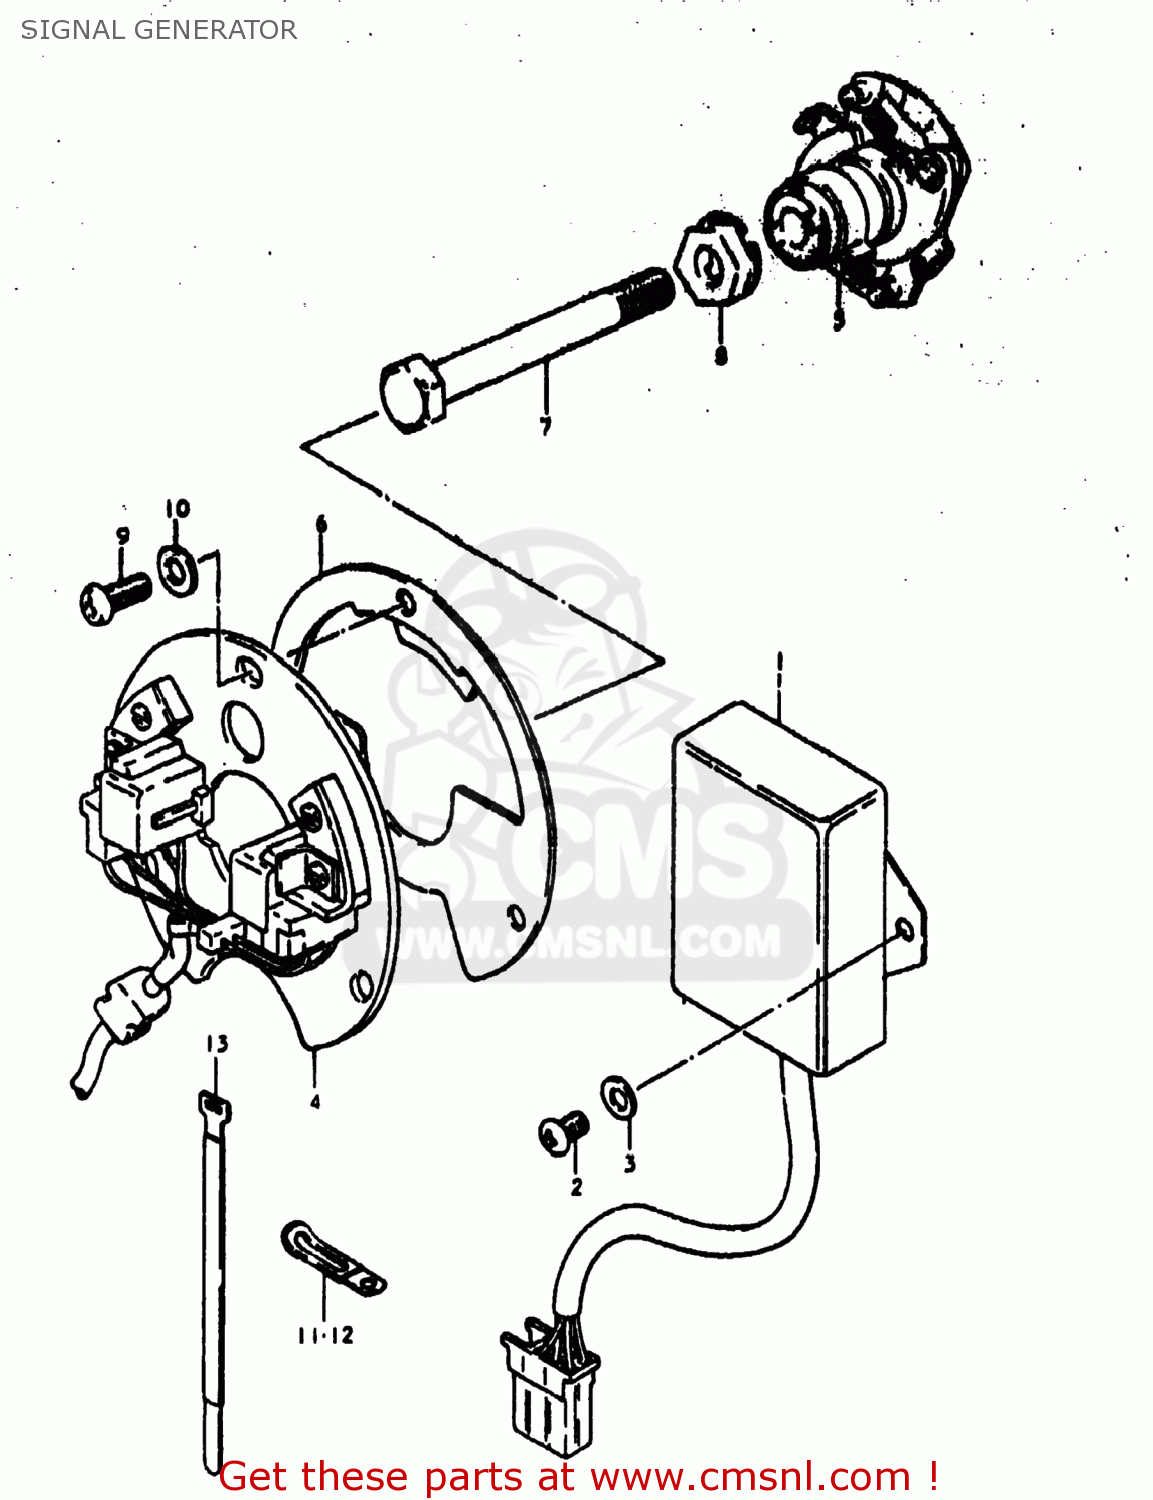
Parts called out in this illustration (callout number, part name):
1	IGNITER UNIT
2	SCREW
3	WASHER
4	SIGNAL GENERATOR ASSEMBLY
5	GOVERNOR ASSEMBLY
6	PLATE,TIMING
7	BOLT
8	WASHER
9	SCREW(5X12)
10	WASHER
11	CLAMP
12	CLAMP
13	CLAMP
